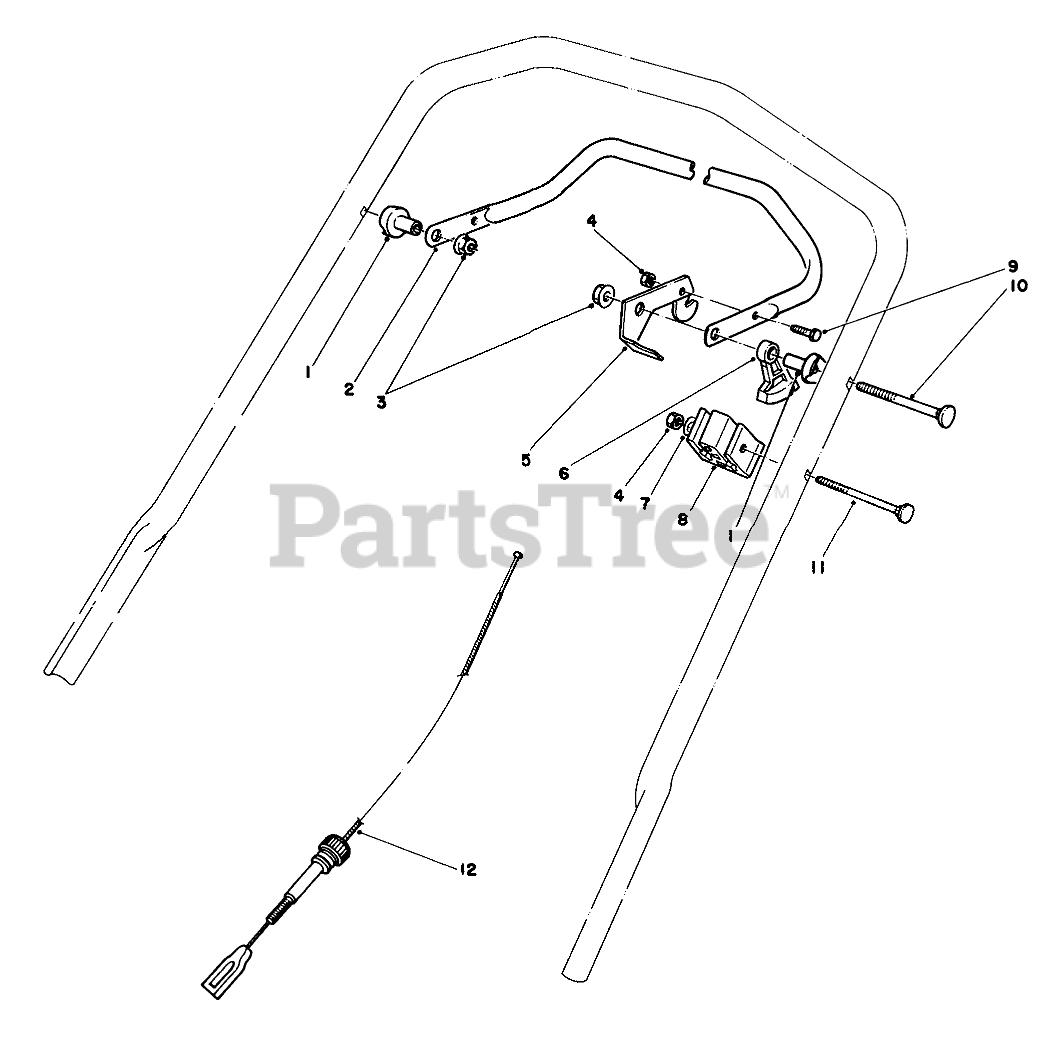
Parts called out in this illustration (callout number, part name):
1	SPACER-SUPPORT
2	Bar-Control
3	NUT-LOCK, NI
4	NUT-LOCK, NI
5	CONTROL LEVER
6	LEVER-TRACTION
7	WASHER-FLAT
8	SUPPORT-CABLE
9	SCREW-HH
10	5/16-18 X 2 HNDLE SCREW
11	HANDLE SCREW
12	CABLE-TRACTION
